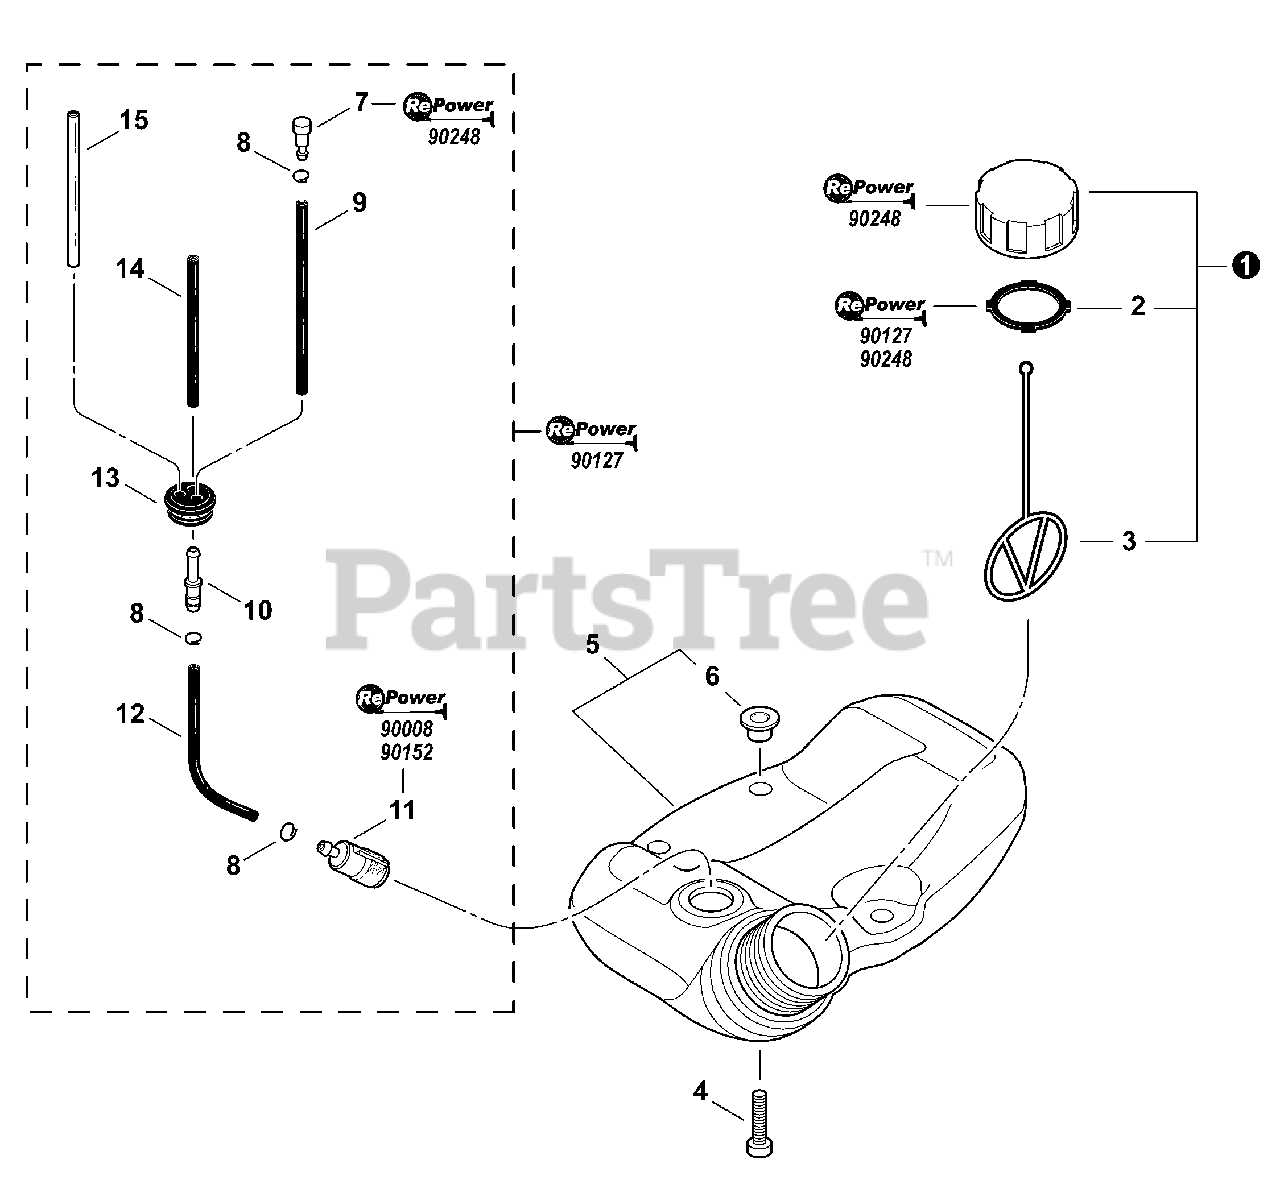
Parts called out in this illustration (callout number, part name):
1	CAP ASSY
2	GASKET, CAP
3	CONNECTOR, CAP
4	SCREW - 5×20
5	FUEL TANK ASSY
7	VENT, FUEL TANK
8	CLIP - 6
9	PIPE - 3×5×90 -- BLACK
10	CONNECTOR, FUEL PIPE
11	FILTER, FUEL
12	PIPE - 3×5×130 -- BLACK
14	PIPE - 3×5×74 -- BLACK
15	PIPE - 3×6×80 -- CLEAR
